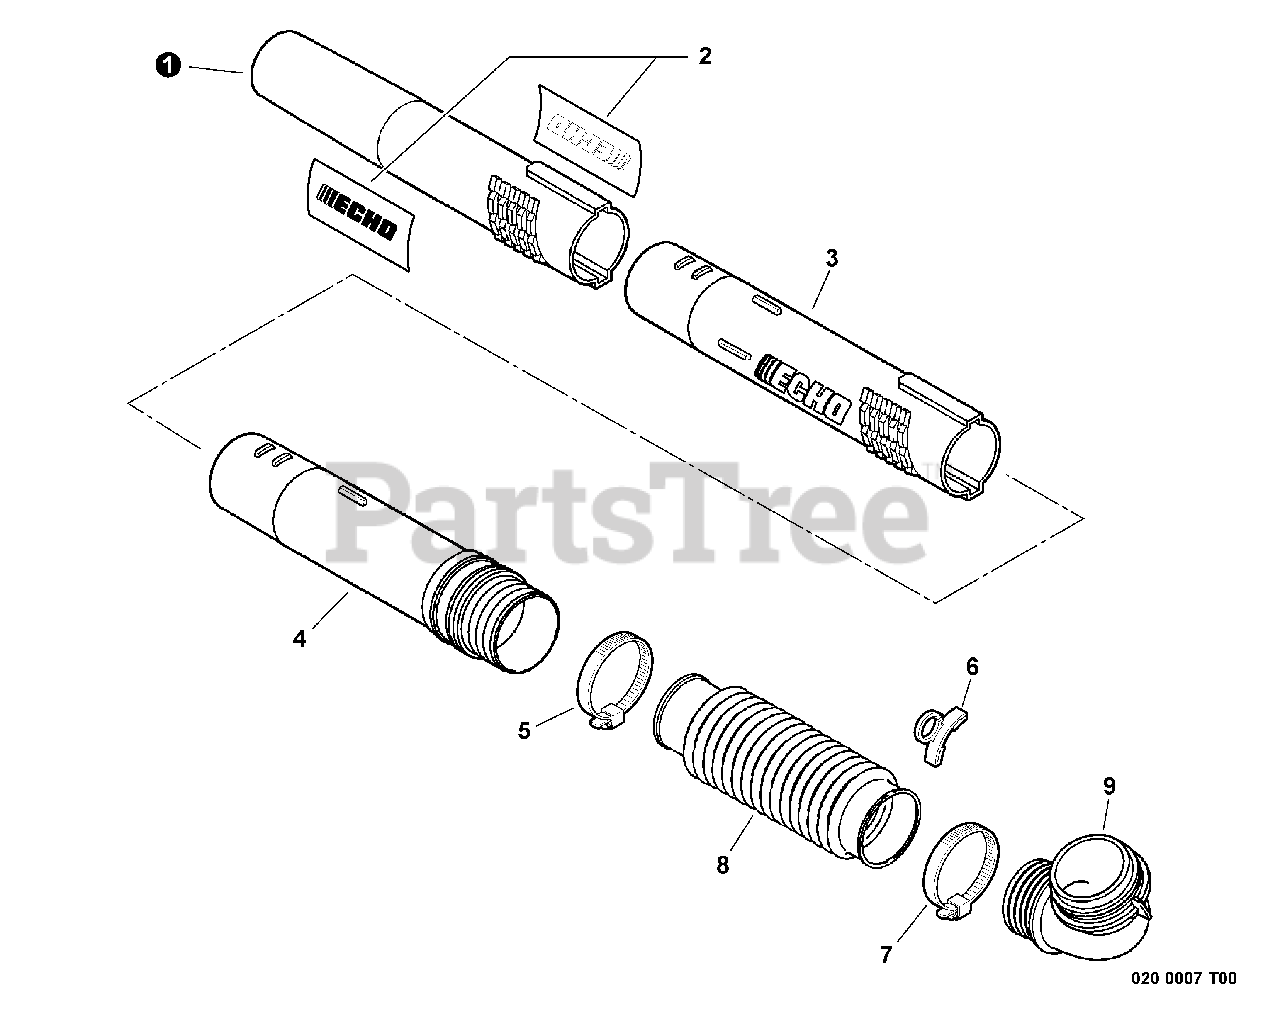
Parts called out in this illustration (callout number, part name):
1	TUBE, BLOWER - NOZZLE
2	LABEL, ECHO BLOWER TUBE
3	TUBE, BLOWER - STRAIGHT
4	TUBE, BLOWER - SWIVEL
5	CLAMP 58.7 MM / 82.5 MM
6	CLIP, CABLE
7	CLAMP - BAND
8	TUBE, BLOWER - FLEXIBLE
9	TUBE, BLOWER - ELBOW
